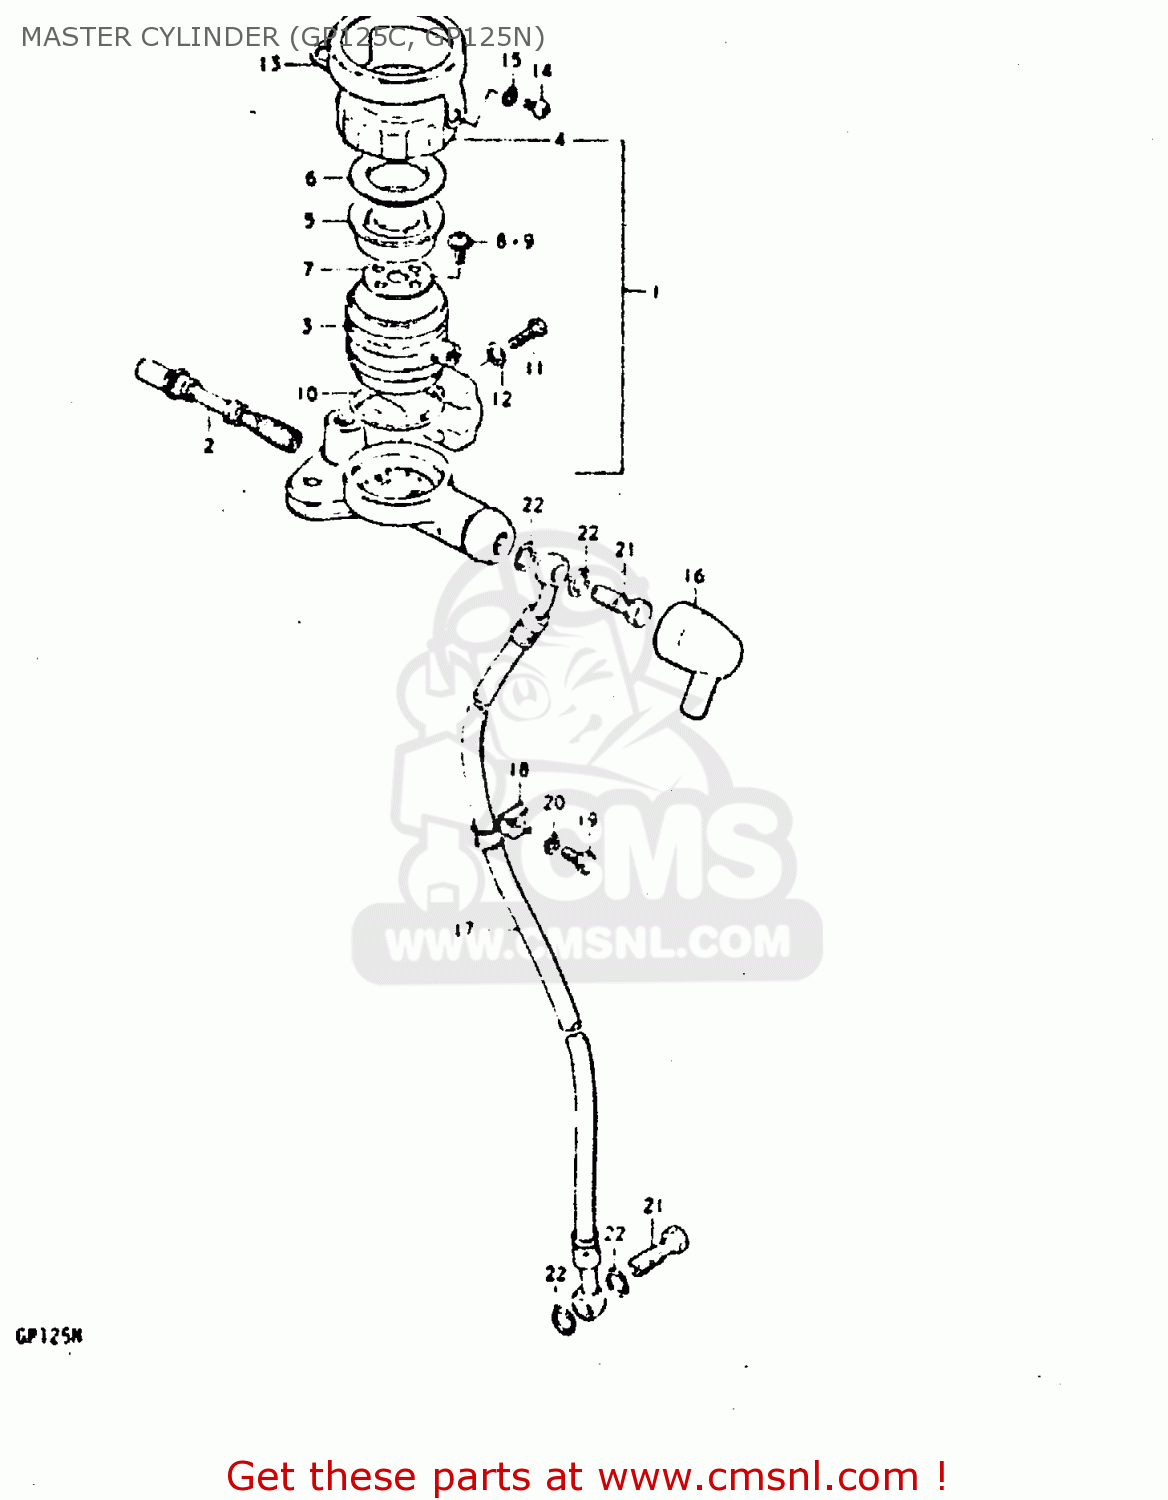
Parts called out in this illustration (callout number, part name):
1	CYLINDER ASSY, MASTER
2	PISTON & CUP SET
3	RESERVOIR
4	CAP
5	DIAPHRAGM
6	PLATE,DIAPHRAGM
7	PLATE
8	SCREW,MASTER CYLINDER
9	SCREW,MASTER CYLINDER
10	O RING
11	BOLT
12	WASHER
13	LOCK PLATE, CAP
14	SCREW
15	LOCK WASHER
16	BOOT,MASTER CYLINDER
17	HOSE, BRAKE
18	CLAMP,BRAKE HOSE
19	BOLT
20	LOCK WASHER
21	BOLT UNION
22	WASHER
